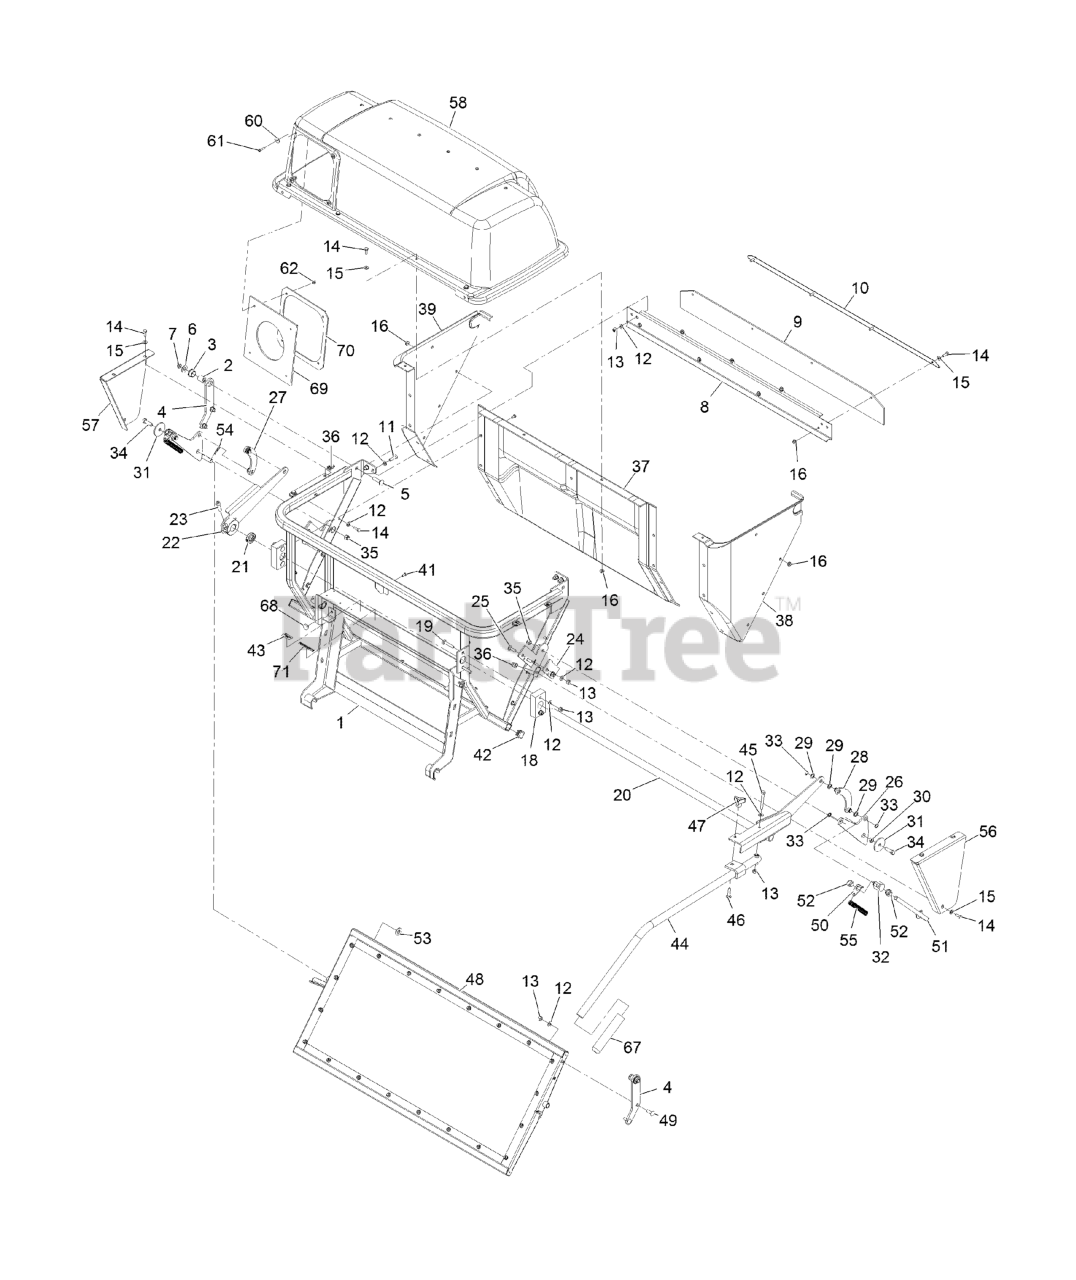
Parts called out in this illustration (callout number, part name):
1	FRAME ASM
2	PIN-PIVOT, HINGE
3	BEARING
4	PLATE-HINGE
5	SCREW-CARR
6	WASHER-FLAT
8	PLATE-REAR
9	SEAL-DOOR
10	STRAP-HOLD DOWN
11	SCREW-HH
12	WASHER-PLAIN
13	NUT-LOCK, NI
14	SCREW-HH
15	WASHER-FLAT
18	BEARING
19	BOLT-CAR
20	BELLCRANK
21	SHAFT-COLLAR
23	SCREW-HSH
24	STOP-LINKAGE
25	BOLT-CARR
26	ARM-LINKAGE, DOOR
27	LINK-RH
28	LINK-LH
29	WASHER-NYLON
30	BEARING-LINKAGE, PIVOT
32	TRUNNION-LINK
33	RING-RETAINING
34	SCREW-HH
35	NUT-LOCK, NI
37	PANEL-BAGGER
38	PANEL-BAGGER, LH
39	PANEL-BAGGER, RH
41	RIVET-BLIND
43	Decal-Patent Ttco.Com
44	HANDLE-QD7
45	SCREW-HH
46	Bolt-Carriage 5/16-18 X 1 1/4
47	KNOB-3 PRONG
48	Asm, Door
49	SCREW-CARR
50	ANCHOR-SPRING
51	LINK-DOOR
52	NUT-HEX
53	WASHER-FLAT
54	PIN-COTTER
58	ASM, HOOD
60	WASHER-FLAT
61	SCREW-PPH
62	NUT-LOCK, NI
67	HANDLE-GRIP
69	SEAL-CHUTE
70	CLAMP-SEAL
71	DECAL-WARNING
